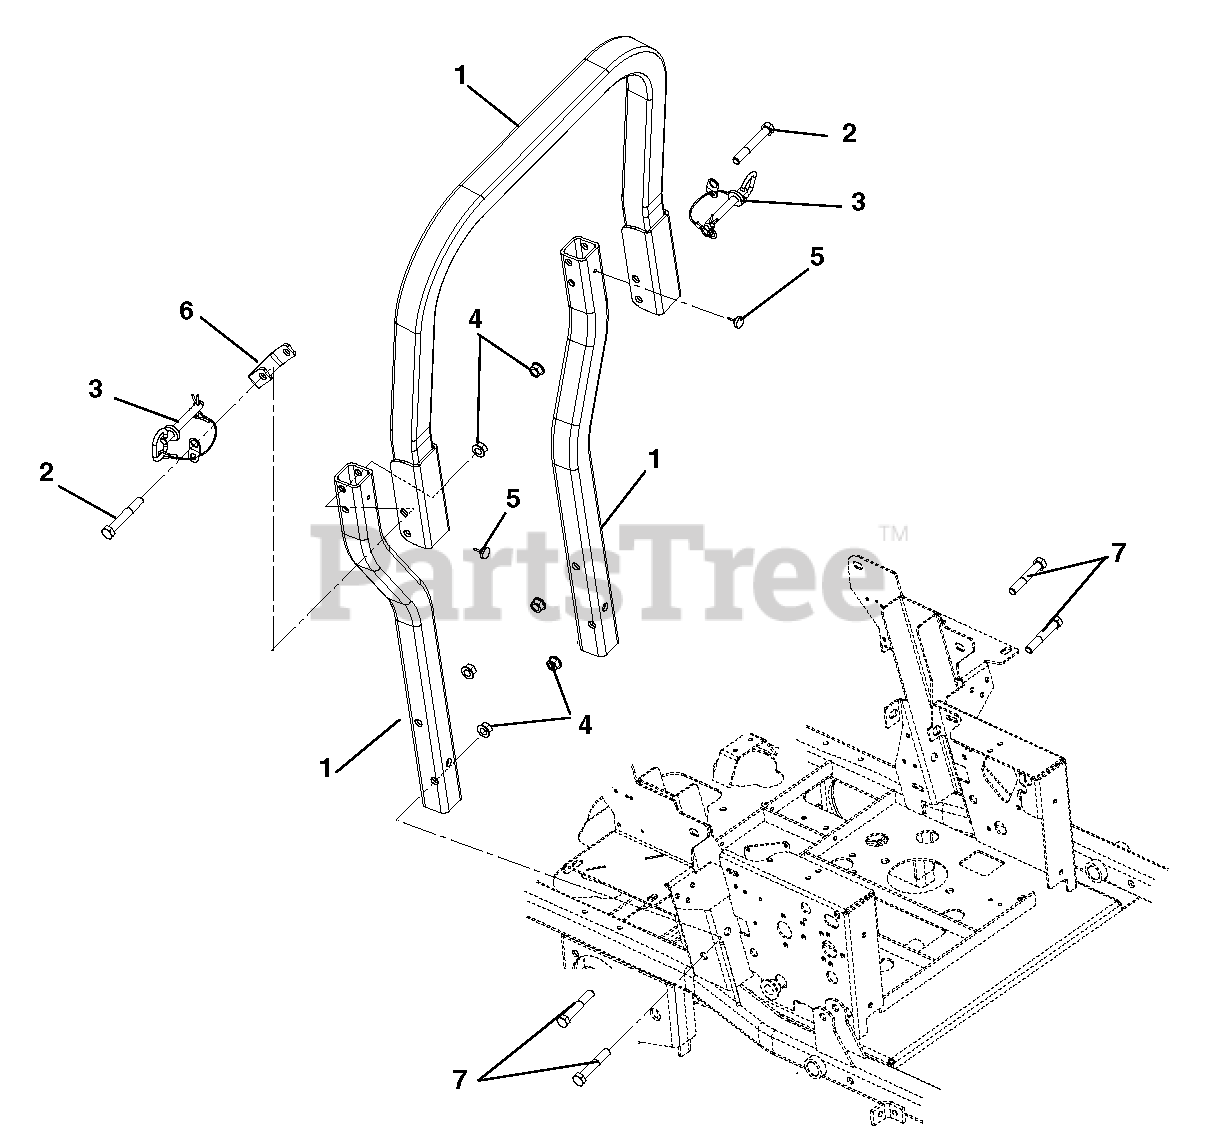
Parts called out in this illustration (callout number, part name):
1	ROPS, PM200 Replacement
2	Bolt, Hex .50-13 x 3.50 Grade 5
3	Assembly, ROPS PIN/LANYARD
4	Nut, Locking-Top-Flange .50-13
5	Bumper, ROPS Rubber
6	Bracket, ROPS Stop, Pro-Master
7	Bolt, Hex .50-13 x 3.00 Grade 5
